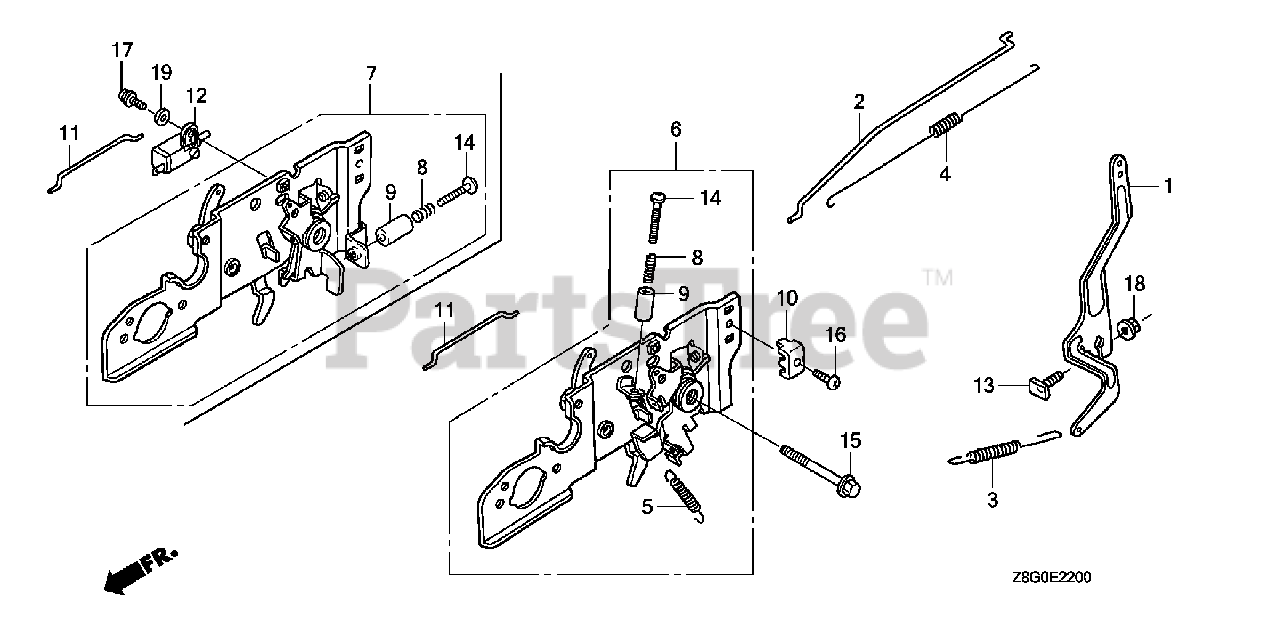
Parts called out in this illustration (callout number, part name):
1	ARM, GOVERNOR
2	ROD, GOVERNOR
3	SPRING, GOVERNOR
4	SPRING, THROTTLE RETURN
5	SPRING, LEVER
6	BASE, CONTROL
8	SPRING, CONTROL ADJUSTING
9	COLLAR, STOPPER
10	HOLDER, CABLE
11	ROD, CHOKE
13	BOLT, GOVERNOR ARM
14	SCREW, RECESSED (5X28)
15	BOLT, FLANGE (6X45) (CT200)
16	SCREW, PAN (5X16)
18	NUT, FLANGE (6MM)
